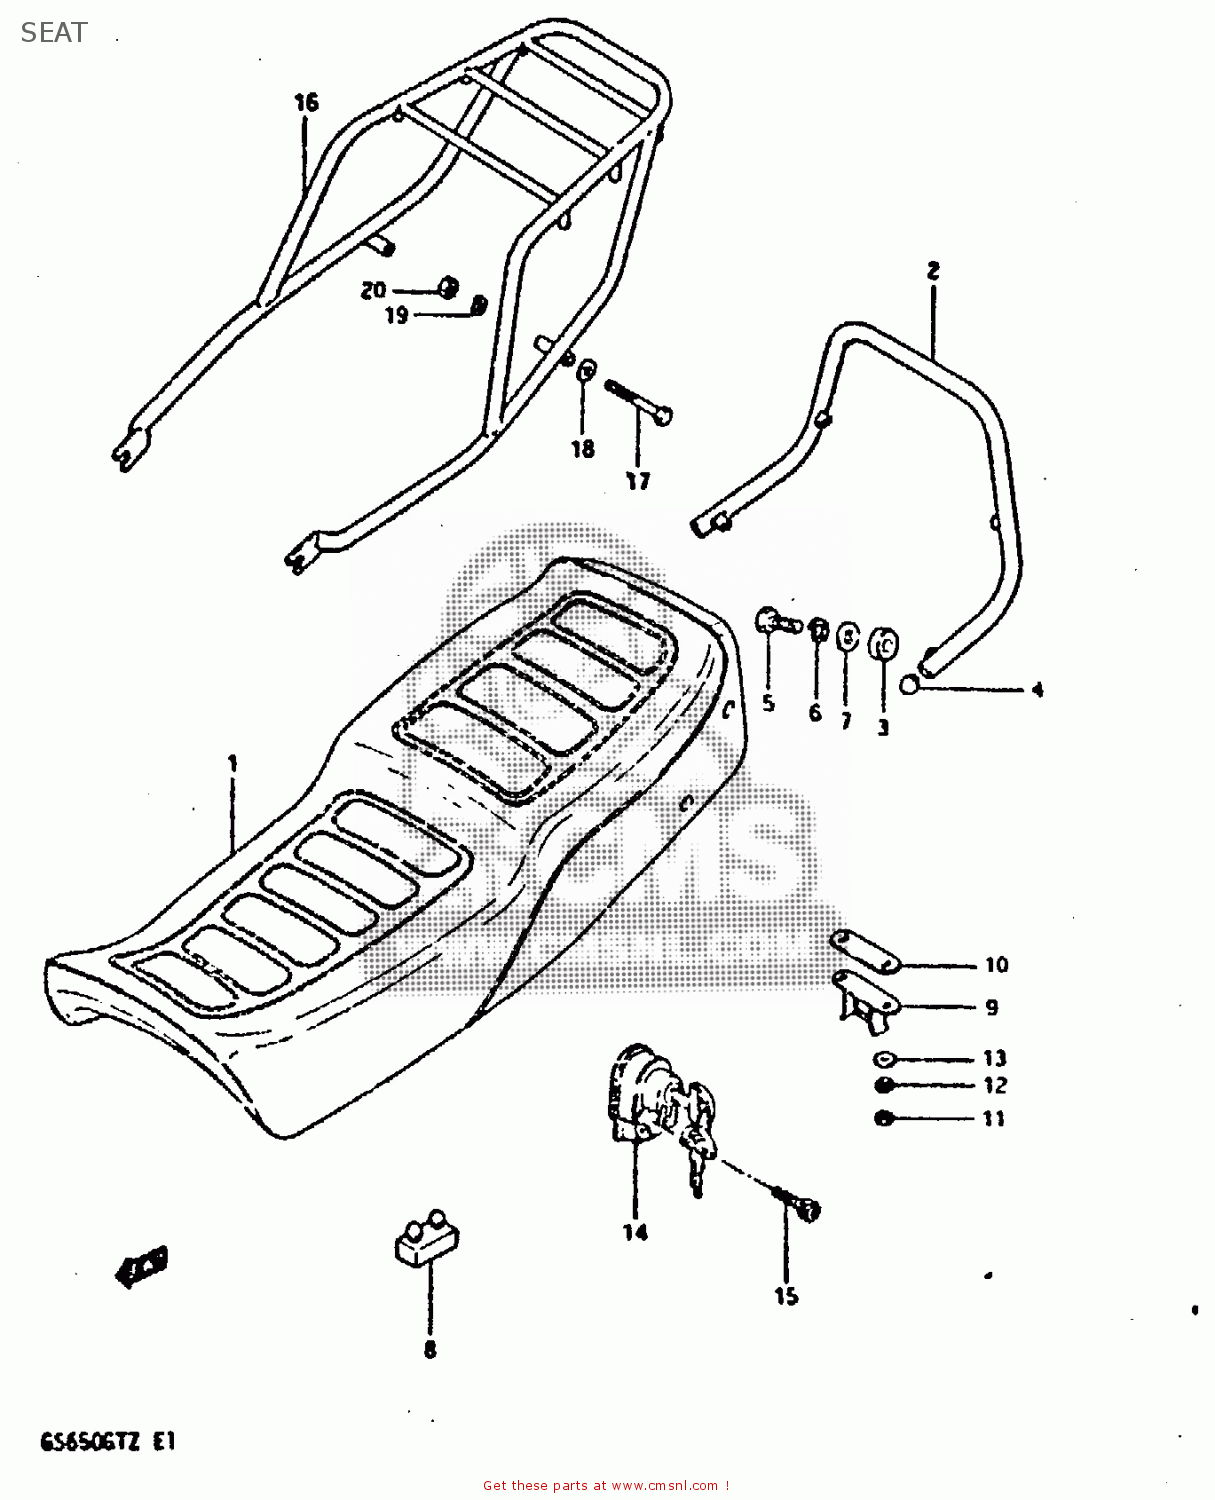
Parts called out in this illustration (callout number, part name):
1	SEAT (BLACK)
2	HANDLE,PILLION RIDER
3	CUSHION
4	END,SHEET HANDLE
5	BOLT
6	LOCK WASHER
7	WASHER
8	CUSHION
9	STRIKER,SEAT LOCK
10	SHIM,SEAT LOCK STRIKER
11	NUT 6MM
12	LOCK WASHER
13	WASHER
14	LOCK ASSY,HELMET
15	BOLT 5X25
16	CARRIER, SPORTS
17	BOLT
18	WASHER
19	LOCK WASHER
20	NUT
